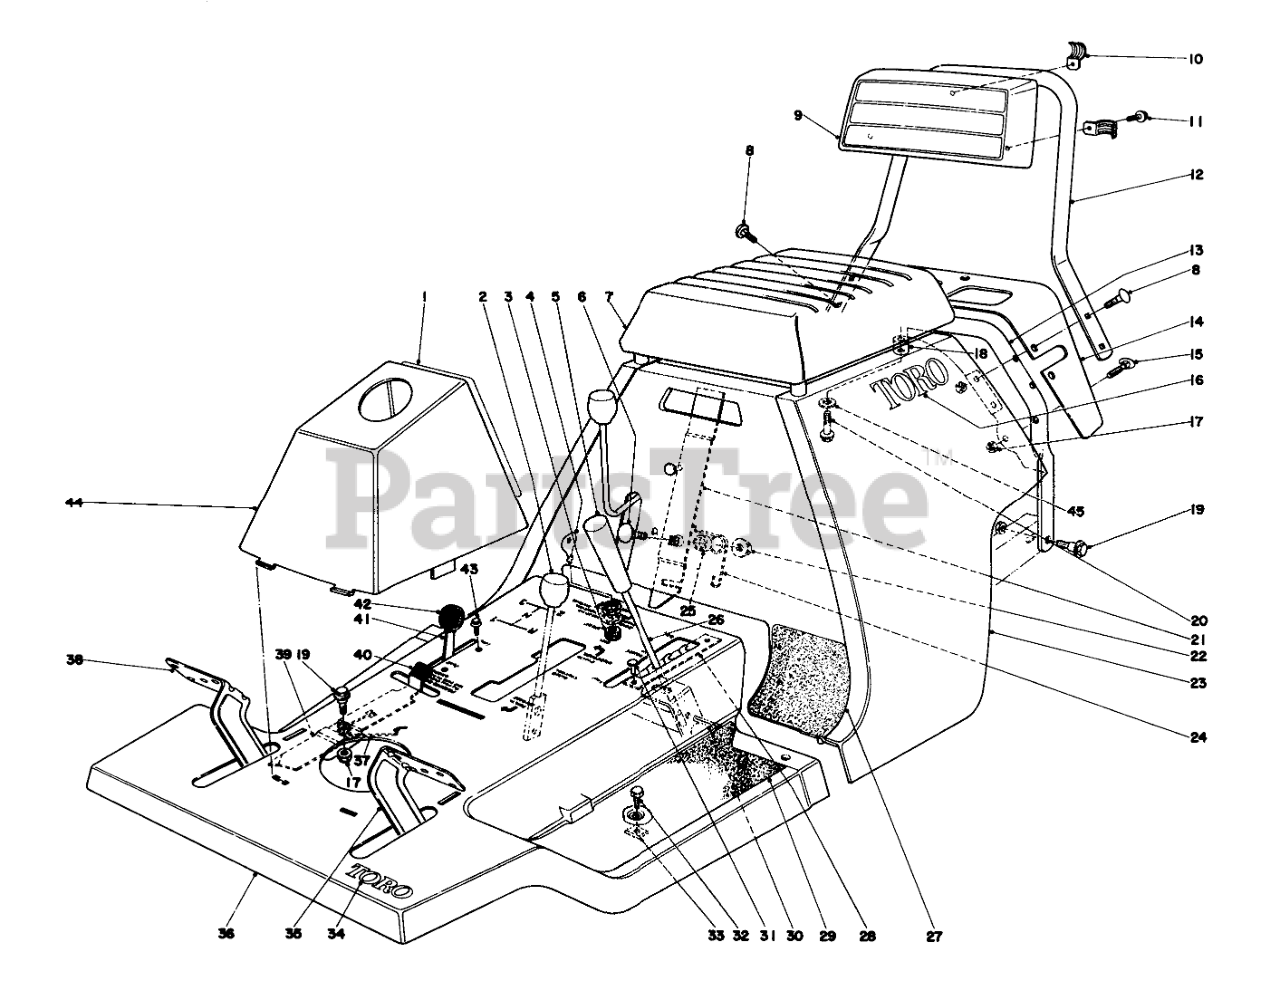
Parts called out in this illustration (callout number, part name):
1	Decal Tower
3	STARTER SWITCH
4	Key
5	KNOB-CONTROL
6	BOLT-CARR
8	SCREW-CARR
9	Backrest
10	Clamp Conduit
11	SCREW-HHF
12	Handle Upper
13	Handle Lower
14	Extension Rear Body
15	HANDLE SCREW
16	Decal
17	NUT-LOCK, CONE
18	Spacer
19	SCREW-SHOULDER
20	HEX FLANGE SCREW
21	Handle Latch
22	NUT-HF
23	Rear Body
24	Latch Return Spring
25	Spacer
26	Height of Cut Lever
27	Heel Pad L.H.
28	Height Adjustment Plate
29	Foot Tread L.H.
30	Pin-Roll
32	Hex Hd. Capscrew
33	NUT-TINNERMAN
34	DECAL
35	Clutch Pedal
36	Body-Front (Incl. Ref. #28 & 31)
37	SPRING-PARKING BRAKE
38	Brake Pedal
39	Parking Brake
40	TIP-PARKING BRAKE
41	Throttle Control (Incl. Ref. #42)
43	8X1/2 SELF TAP SCREW
44	Tower
45	WASHER-FLAT
